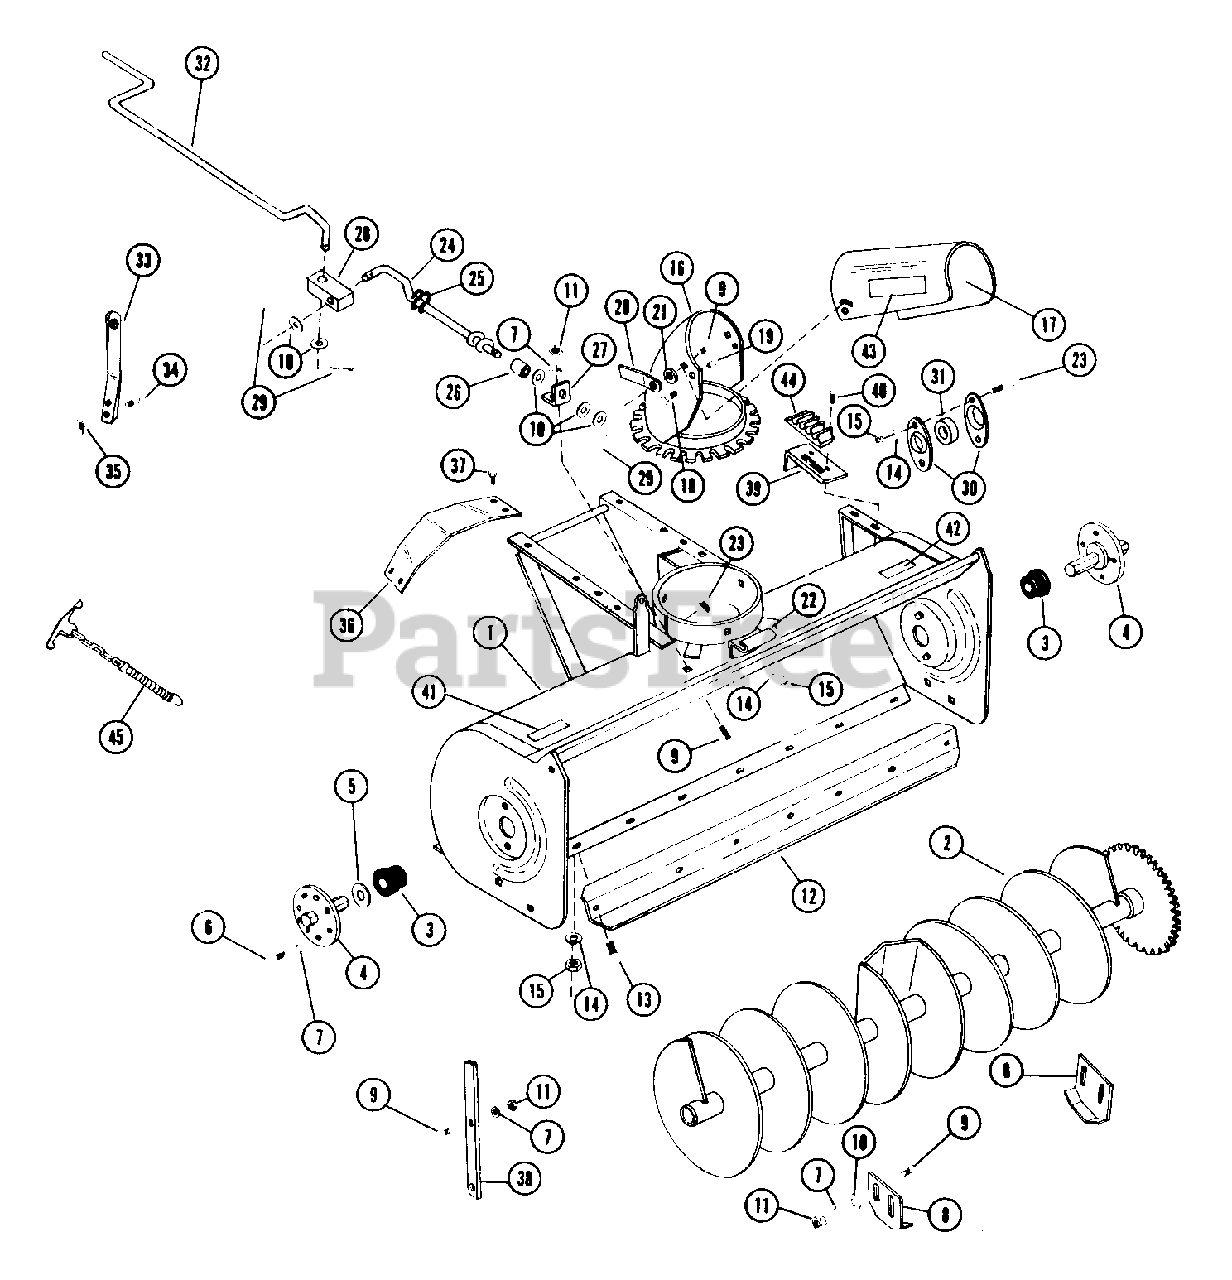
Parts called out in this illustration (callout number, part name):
1	54 IN FRAME
1	AUGER HOUSING ASSEMBLY
2	LATCH PIN
2	48 ST AUGER
3	BLT-HEX .31-18X1.25 PL GR2
3	BRG-BALL .687X2.25X.80 HEX
4	NUT-LK .312-18 GR A PL
4	MOUNTING PLATE
5	PIN-COTR .12X1.0 PL
5	WSHR-FL-STL.812X1.500X.139
6	SG-COMP .080X.85X1.44
6	BLT-HEX .38-16X.75 PL GR5
7	WSHR-LK .375X.094 MED PL
8	PIVOT PLATE
8	SKID SHOE
9	BLT-RDHDSQNK .31-18X.75 SHT PL
9	BLT-RDHDSQNK .38-16X.75 SHT PL
10	SUPPORT
10	WSHR-FL-STL .438X1.0X.083 PL
11	NUT-HEX .375-16
12	PIN-COTR .12X.75 PL
12	WEAR PLATE
13	WSHR-FL-STL .438X1.0X.083 PL
13	BLT-RDHDSQNK .31-18X.75 GR5 PL
14	WSHR-LK .312X.097 PL HVY
15	UNIVERSAL BLOCK JOINT
15	NUT-HEX .312-18
17	PIN-COTR .18X1.0 PL
17	CHUTE DEFLECTOR ASSEMBLY
18	BLT-HEX .38-16X1.00 PL
18	BLT-HEX .25-20X.50 PL GR5
19	SPACER .406X.749X.162
19	NUT-LK TOP .250-20 PL
20	WSHR-LK .375X.094 MED PL
20	LOCKING LEVER
21	NUT-HEX .375-16
21	WSHR (ND)
22	54 IN BLADE
22	SPOUT RING HOLDER
23	WEAR PLATE
23	BLT-RDHDSQNK .31-18X.75 SHT PL
24	BLT-RDHDSQNK .31-18X1.00 PL
24	DISC CONTROL COIL
25	NUT-HEX .312-18
25	SG-COMP .094X.75X2.50 WLD36
26	WSHR-LK .312X.097 PL HVY
26	SPLIT SPACER
27	JACK PIN
27	BRACKET
28	PIN-COTR .12X1.0 PL
28	UNIVERSAL BLOCK JOINT
29	PIN-HAIR INT .14X.4X2.75
29	PIN-COTR .09X.75 PL
30	SKID SHOE
30	MTG-FLG 2 HOLE 42MM
31	BLT-RDHDSQNK .38-16X1.0 PL
31	BRG-BALL .75X1.65X.50
32	ARM, LIFT LINK
32	CHUTE CONTROL HANDLE
33	SUPPORT
34	SG-TENS .187X1.50X9.94 WLD 40
34	BLT-RDHDSQNK .38-16X1.0 GR5PL
35	SUPPORT
35	NUT-WING .375-16 ZCC
36	PTO SHIELD
37	SCR-TAP .250-20X.50 HH F
39	NUT-WING .375-16 ZCC
40	GRIP
40	SCR-TAP .250-20X.50
41	ARIENS SCRIPT NAME PLATE
42	DASH DECAL
43	DECAL WARNING
44	SHEAR BOLT HOLDER
45	SPRING & CHAIN ASSEMBLY
